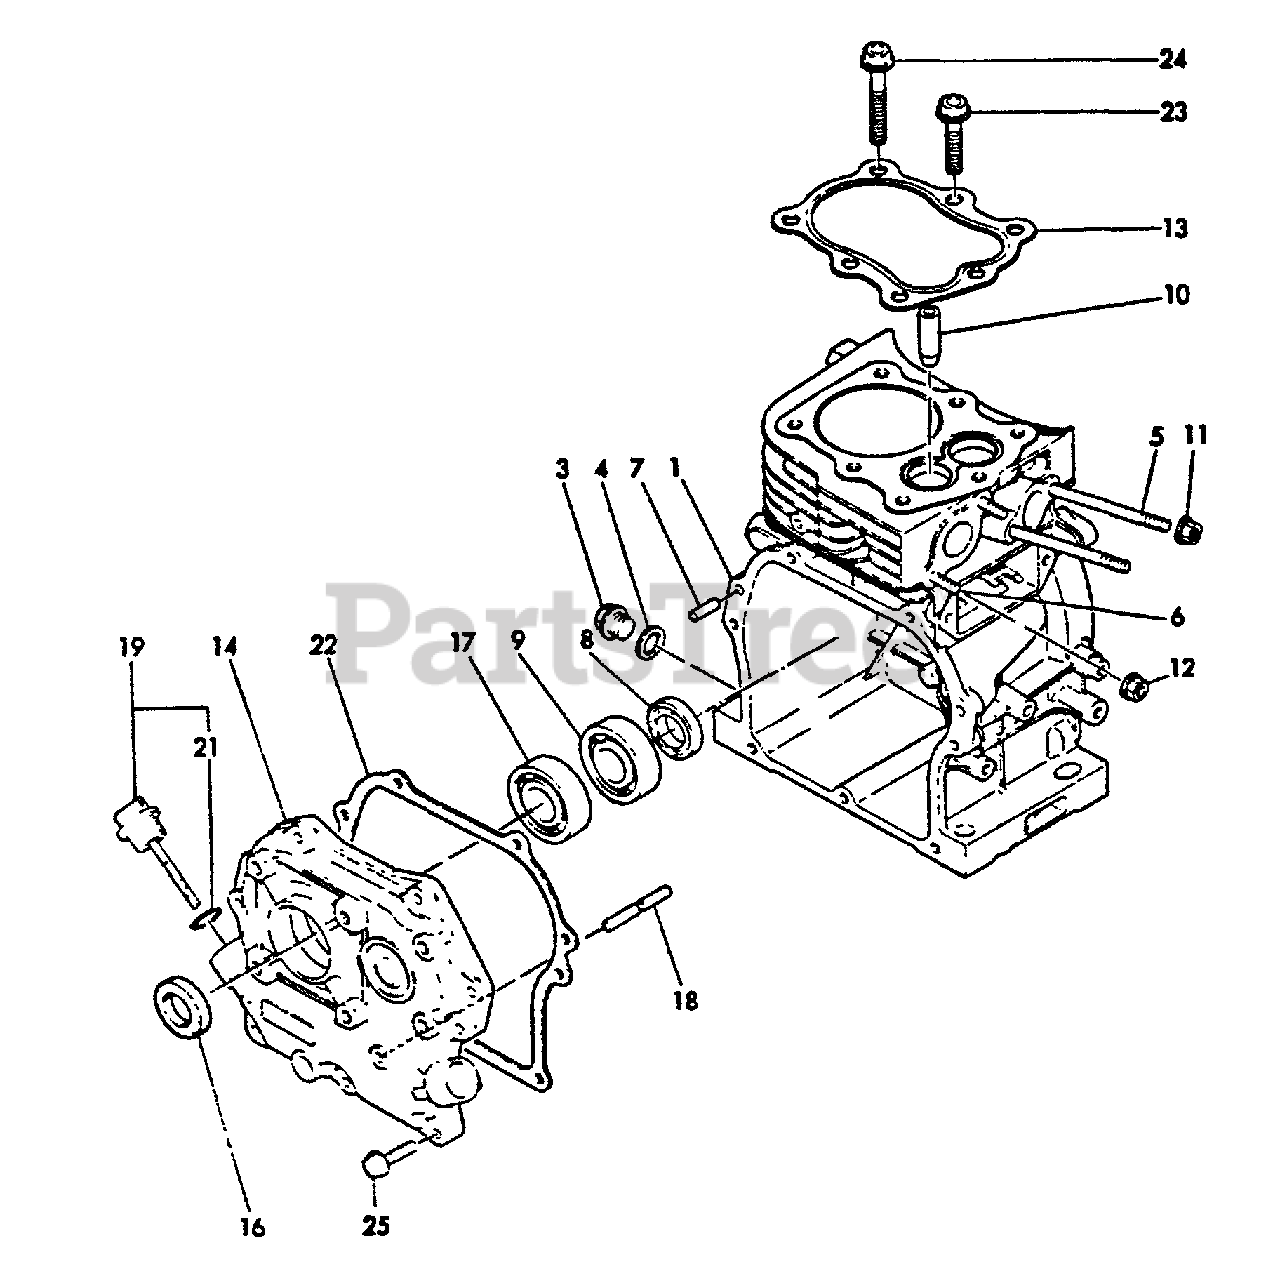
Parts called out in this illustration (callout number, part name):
1	CYLINDER ASSY
3	PLUG, DRAIN
4	GASKET
5	BOLT - 6×70
6	BOLT - 6×16
7	PARALLEL PIN 6×16
8	SEAL, OIL
9	BEARING, BALL 6204 C3
10	GUIDE, VALVE
11	U-NUT M6
12	U-NUT M6
13	GASKET, CYLINDER
14	SIDE COVER ASSY
16	SEAL, OIL
17	BEARING, BALL 6204 C3
18	SHAFT, GOVERNOR
19	CAP ASSY
21	O-RING 1A P-15.0
22	GASKET
23	BOLT - 8×38
24	BOLT - 8×60
25	BOLT - 6×30
